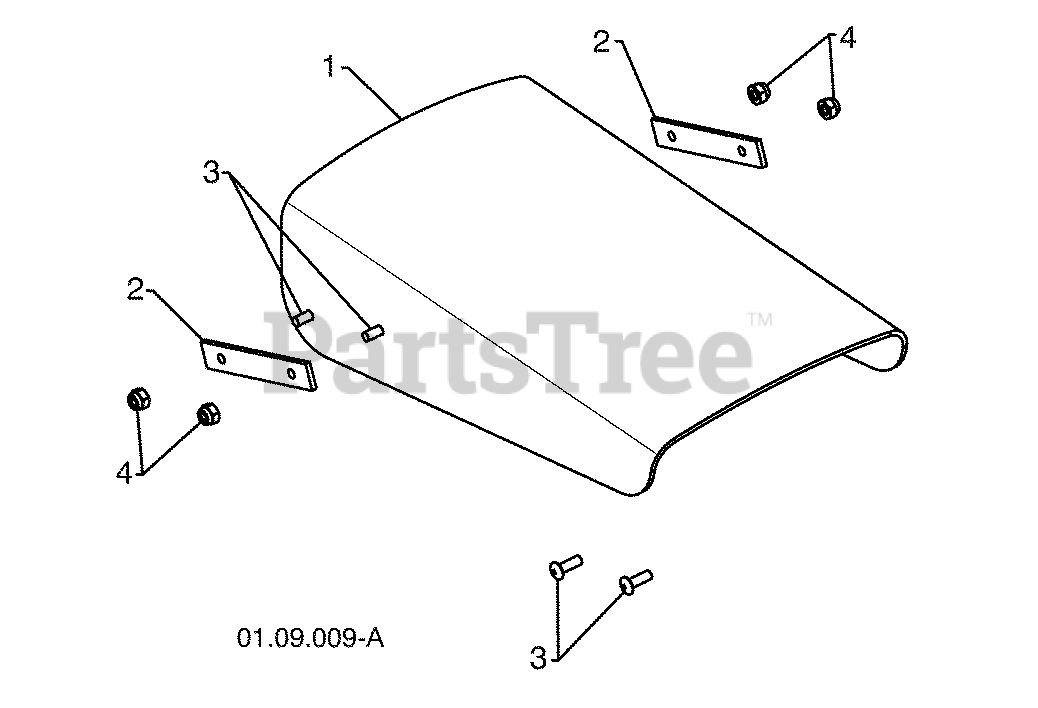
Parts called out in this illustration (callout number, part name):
1	SHIELD DEFLECTOR
2	STRAP
3	SCREW 8-32 X .50
